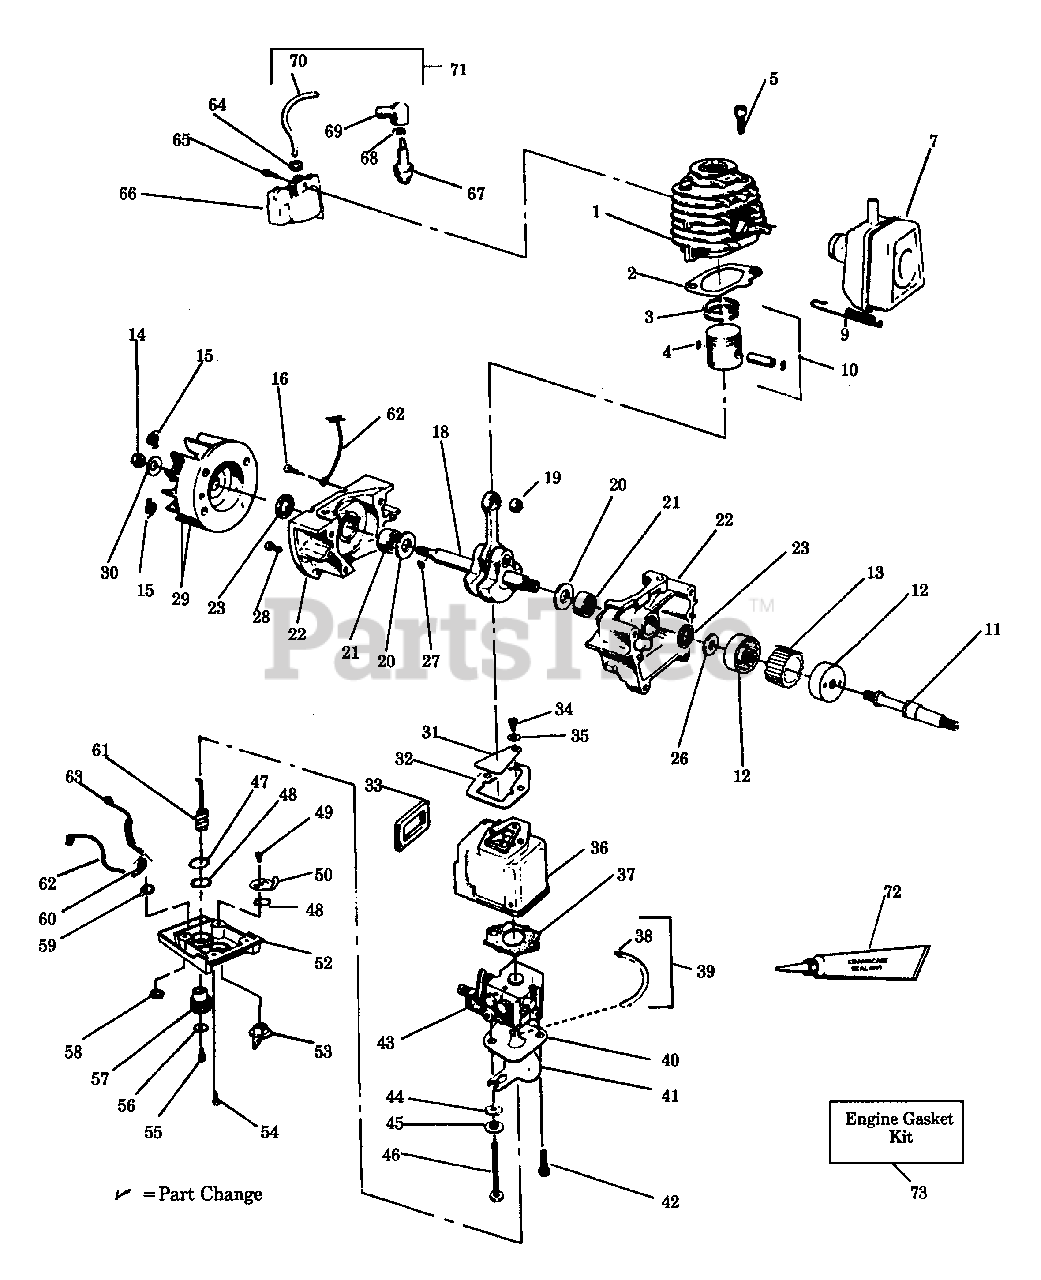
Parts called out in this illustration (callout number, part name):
1	Cylinder - Model 22HB
1	Cylinder - Model 28HBV
2	Cylinder Gasket
3	Piston Ring - Model 22HB
3	Piston Ring - Model 28HBV
4	Wrist Pin Retainer
7	Muffler Ass'y.
9	Muffler Attachment Spring
10	Piston Kit - Model 22HB
10	Piston Kit - Model 28HBV
12	Shaft Coupling
13	Plastic Coupling
14	Flywheel Nut
15	Starter Dog Spring
18	Crankshaft & Rod Ass'y. - Model 22HB
18	Crankshaft & Rod Ass'y. - Model 28HBV
19	Piston Pin Bearing - Model 28HBV Only
21	Crankshaft Bearing
22	Crankcase Ass'y.
23	Crankcase Seal
26	Coupling Washer
27	Flywheel Key
29	Flywheel Ass'y.
30	Flywheel Washer
31	Reed Valve
32	Carburetor Case to Crankcase Gasket
33	Carburetor Case Seal
34	Screw
36	Carburetor Case
37	Carburetor Gasket
38	Fuel Line Fitting
39	Fuel Line & Fitting Ass'y.
40	Choke Guide Plate
41	Choke Shutter
43	Carburetor
44	Wave Washer
47	Retaining Ring
48	Wave Washer
50	Choke Actuator
52	Carb. Case Cover
53	Choke Knob
57	Throttle Knob
58	Grounding Switch Nut
60	Toggle Switch Kit
61	Throttle Wire Ass'y.
62	Ignition Wire
63	Ground Wire
64	Plug Wire Grommet
65	Screw
66	Ignition Module
67	Spark Plug (RCJ-8)
68	Spark Plug Lead Connector
69	Spark Plug Boot
70	High Tension Lead Wire
71	High Tension Lead Ass'y.
72	Crankcase Sealant
73	Engine Gasket Kit
